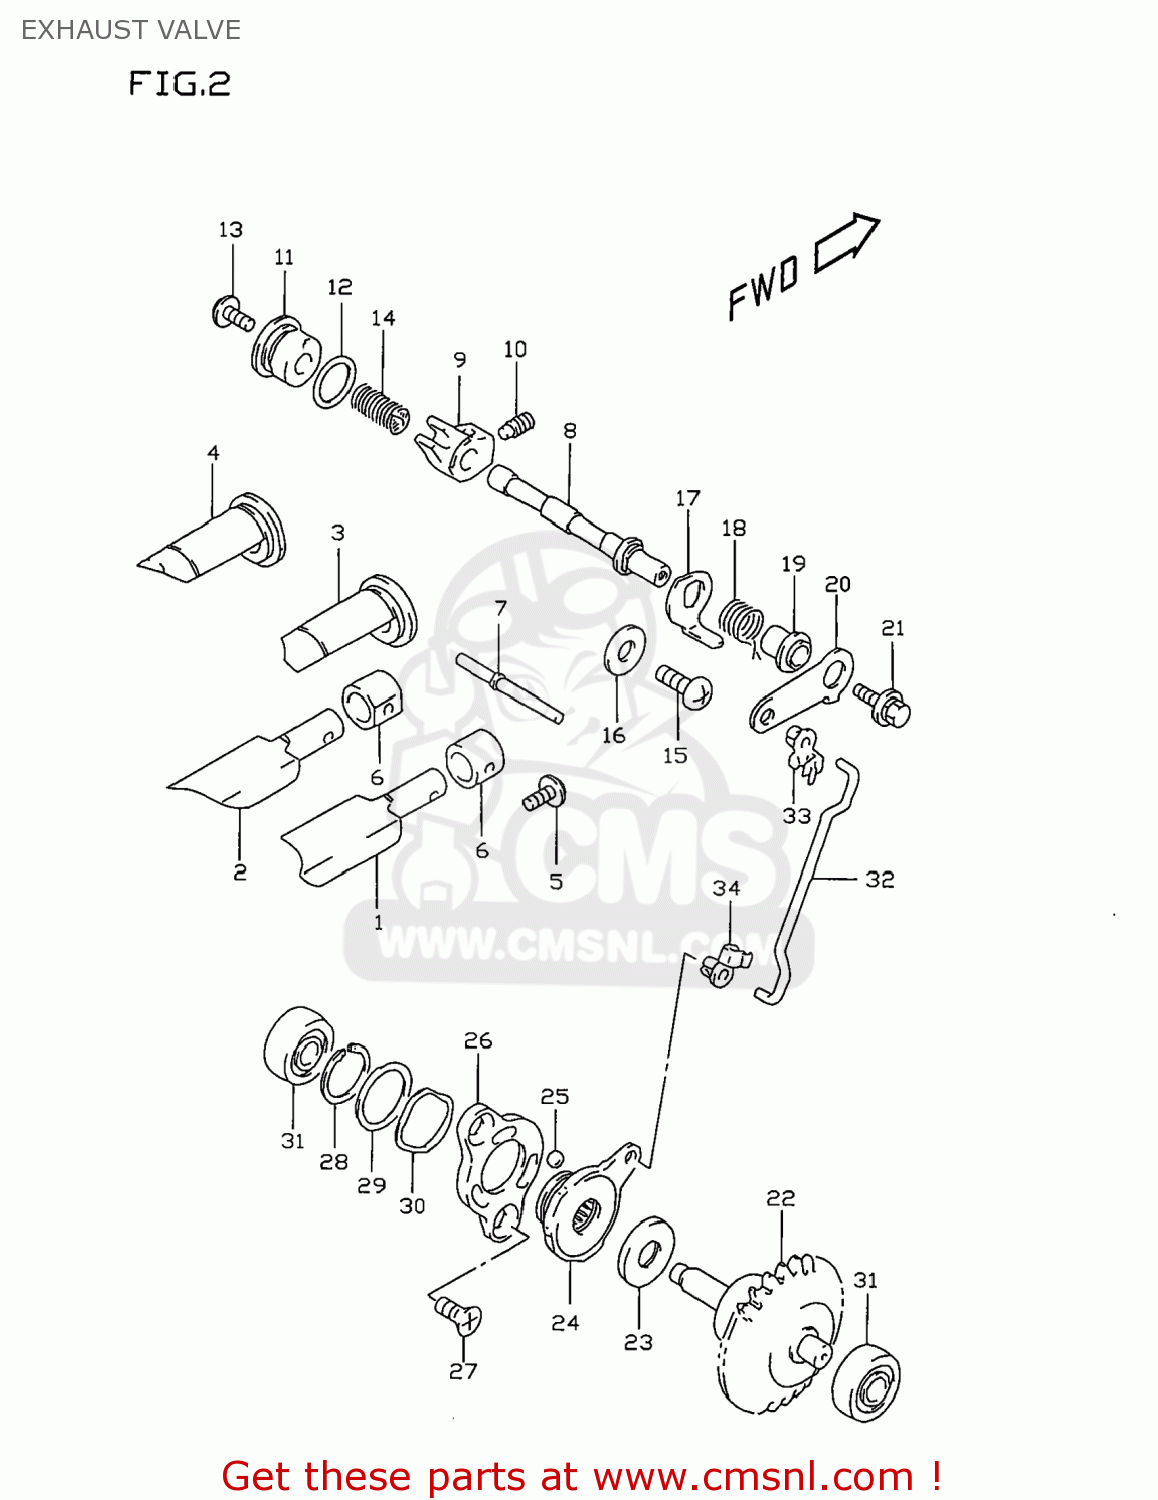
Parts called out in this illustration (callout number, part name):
1	VALVE,EXHAUST,R
2	VALVE,EXHAUST,L
3	GUIDE,EXHAUST VALVE,R
4	GUIDE,EXHAUST VALVE,L
5	SCREW 5X12
6	SPACER,EXHAUST VALVE
7	PIN,EXHAUST VALVE 48.5MM
8	SHAFT,EXHAUST VALVE
9	ARM,EXHAUST VALVE SHAFT
10	SCREW(6X10)
11	CAP,EXHAUST VALVE
12	O RING(D:1.9,ID:14.5)
13	BOLT
14	SPRING
15	SCREW
16	WASHER
17	LEVER,EXHAUST VALVE NO.2
18	SPRING
19	SPACER,EXHAUST VALVE
20	LEVER,EXHAUST VALVE NO.1
21	BOLT(5X12)
22	GOVERNOR ASSEMBLY,EXHAUST
23	BEARING(10X22X2.8)
24	ACTUATOR,EXHAUST VALVE
25	BALL
26	STARTER,EXHAUST VALVE ACTUATOR
27	SCREW(5X10)
28	CIRCLIP
29	SHIM(19.1X25X0.3)
30	WASHER
31	BEARING(8X22X7)
32	ROD,EXHAUST VALVE
33	BUSH,EXHAUST VALVE ROD NO.1
34	BUSH,EXHAUST VALVE ROD NO.2
